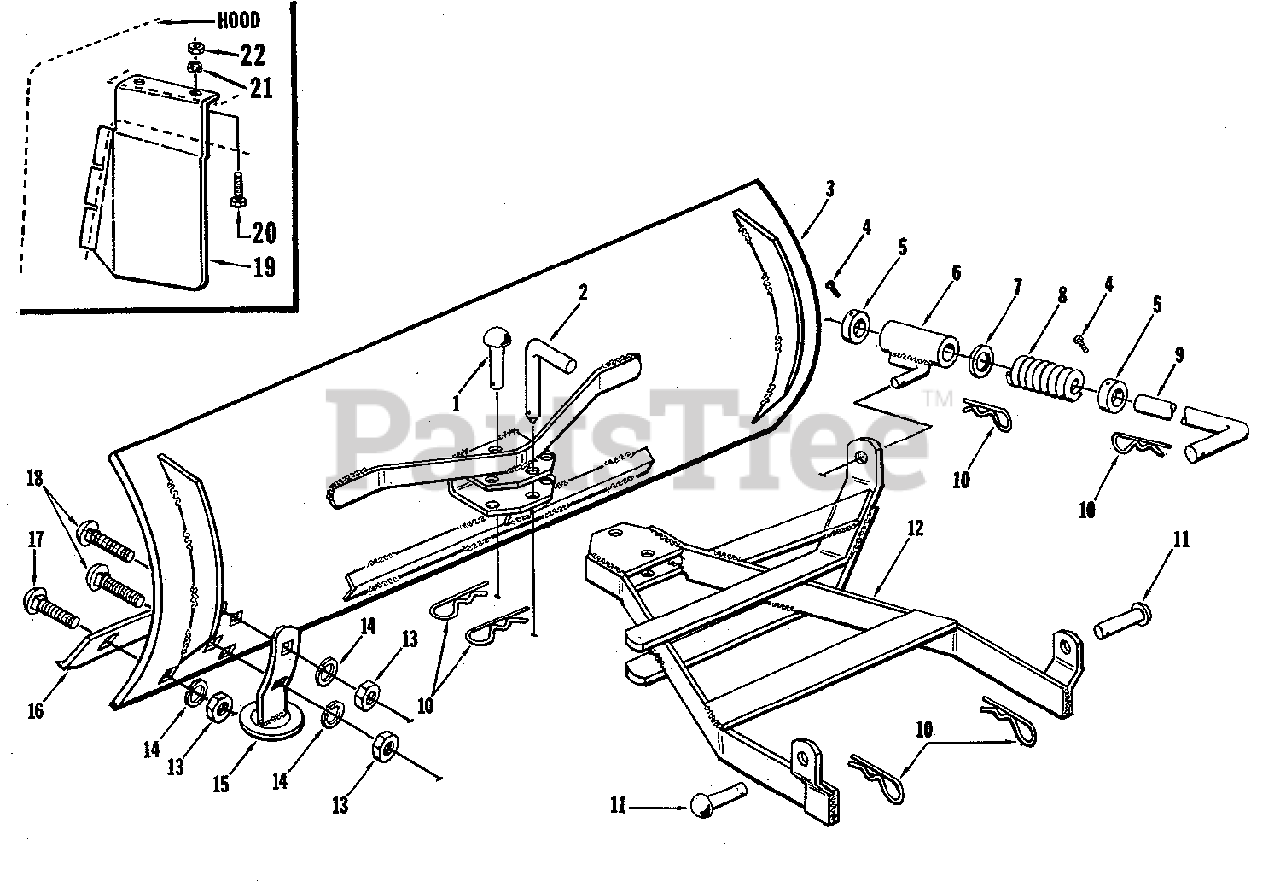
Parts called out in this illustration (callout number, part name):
3	BLADE ASSEMBLY, 42"
4	SCREW, Set, 5/16-18
6	GUIDE ASSEMBLY, Rod
7	WASHER, Flat, 17/32 x 1-1/4
10	PIN, Quick, 1/8
12	BAR ASSEMBLY, Push
13	NUT, Hex, 3/8-16
14	WASHER, Lock, 3/8
15	SHOE ASSEMBLY
17	BOLT, Round Head, 3/8-16 x 3/4
18	BOLT, Round Head, 3/8-16 x 1
19	DEFLECTOR, Snow
20	SCREW, Cap, Hex Head, 1/4-20 x 1/2
21	WASHER, Lock, 1/4
22	NUT, Hex, 1/4-20
